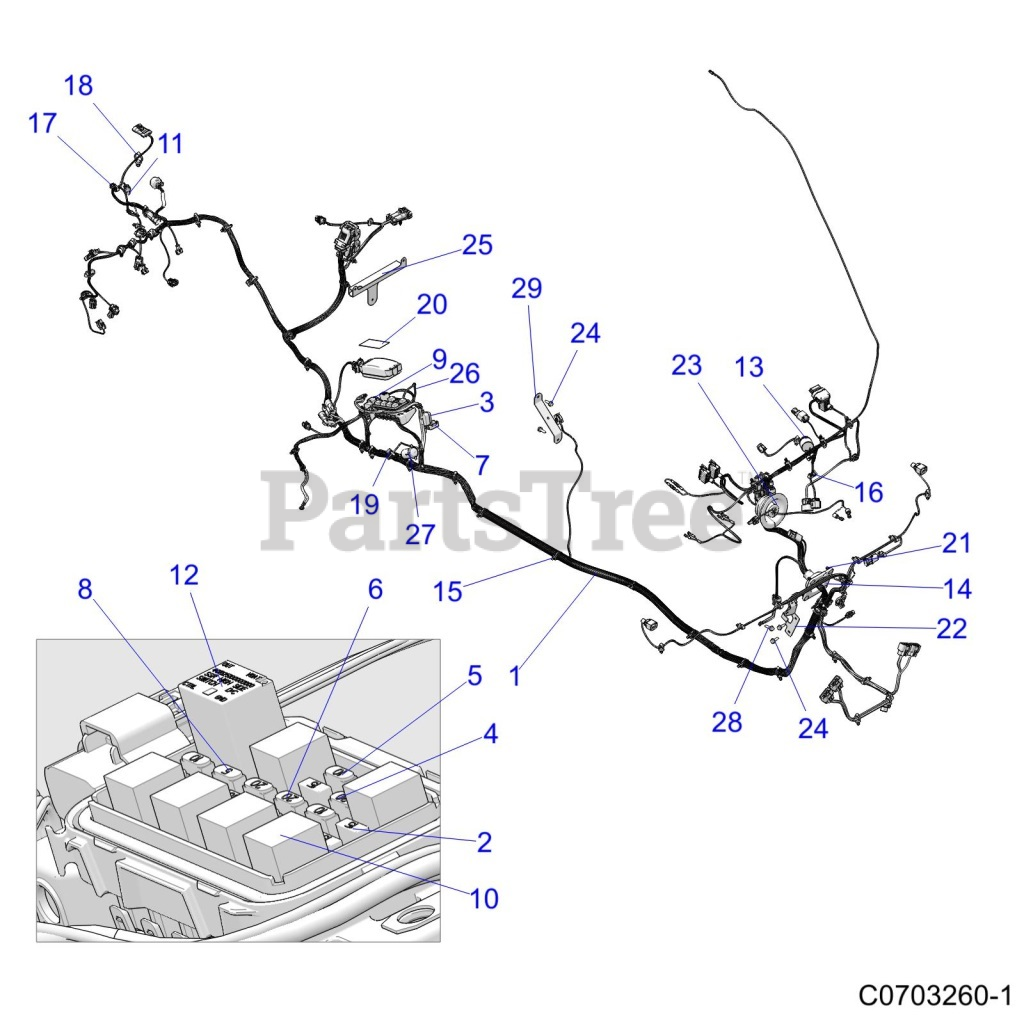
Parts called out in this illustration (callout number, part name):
1	HARNESS-MAIN,GAS,CREW
2	FUSE, MINI BLADE, 15 AMP
3	BREAKER-CIRCUIT,20 AMP,SEALED
4	FUSE,MAIN,30 AMP,(10)
5	FUSE,IGN.10 AMP,(10)
6	FUSE, 20 AMP, PARK
7	BOOT-CIRCUIT BREAKER, RED
8	FUSE-5A,MINI BLADE
9	COVER-DIAGNOSTIC,W/CLIP
10	RELAY-SPST,SERIES 303,SEALED
11	CAP-EVAP CONNECTOR
12	RELAY - SSR 10A
13	ALARM-BRAKE, WARNING
14	GROMMET - 65MM, W/FLANGE, BLK
15	CLIP-ROUTING
16	CLIP-EDGE, 1-3MM THICKNESS
17	CLIP-EDGE, 1-3mm THICKNESS
18	CLIP-FIR TREE, 9, 7-10MM HOLE
19	CLIP-EDGE, 1-3MM THICKNESS
20	DECAL-RELAY/FUSE BLOCK,GAS
21	CLIP-PLASTIC, DART, NYLON
22	BRKT-ROUTING,BLK
23	GROMMET-HOOD LINER,SPLIT
24	SCR-M6X1.0X20,HXHD,FLG,TDFM,BL
25	BRKT-ECU,ZEUS DIESEL
26	CABLE TIE (10)
27	RECEPTACLE-POD MNT,12 VOLT
28	SCR-TFHFL-M6X1.0X25,ZTC
29	BRKT-WIRE GUIDE,BLK
